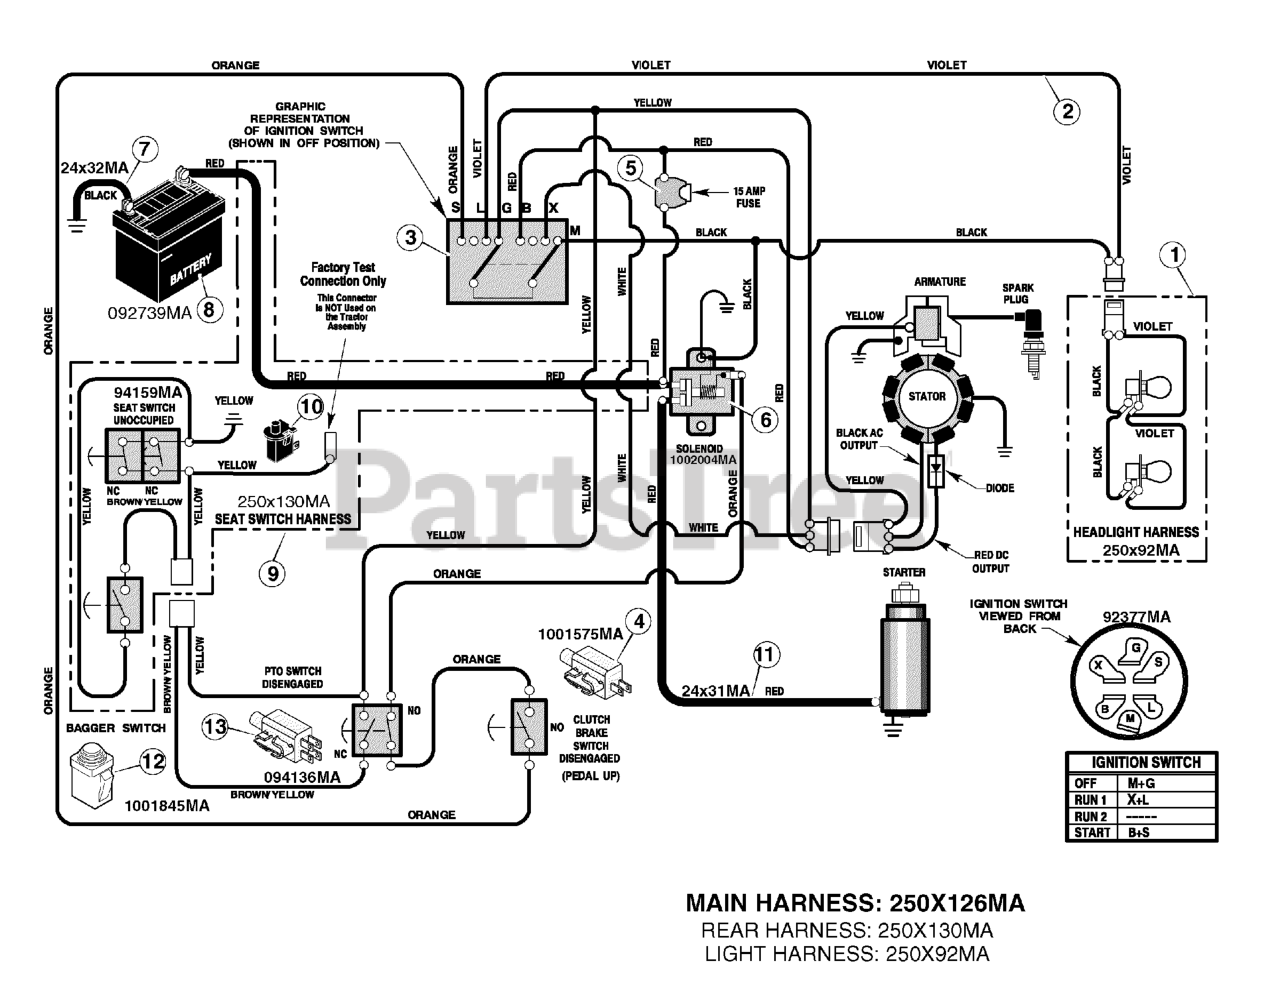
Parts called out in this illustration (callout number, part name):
1	Harness, Light Wire
2	Harness, Chassis Wire
3	Switch, Ignition
4	Switch, Limit Clutch
6	Solenoid
7	Cable, Battery Ground
8	Battery
9	Harness, Seat Switch Wire
10	Switch, Seat Sensor
12	Switch, Bag Sensor
13	Switch, Limit
